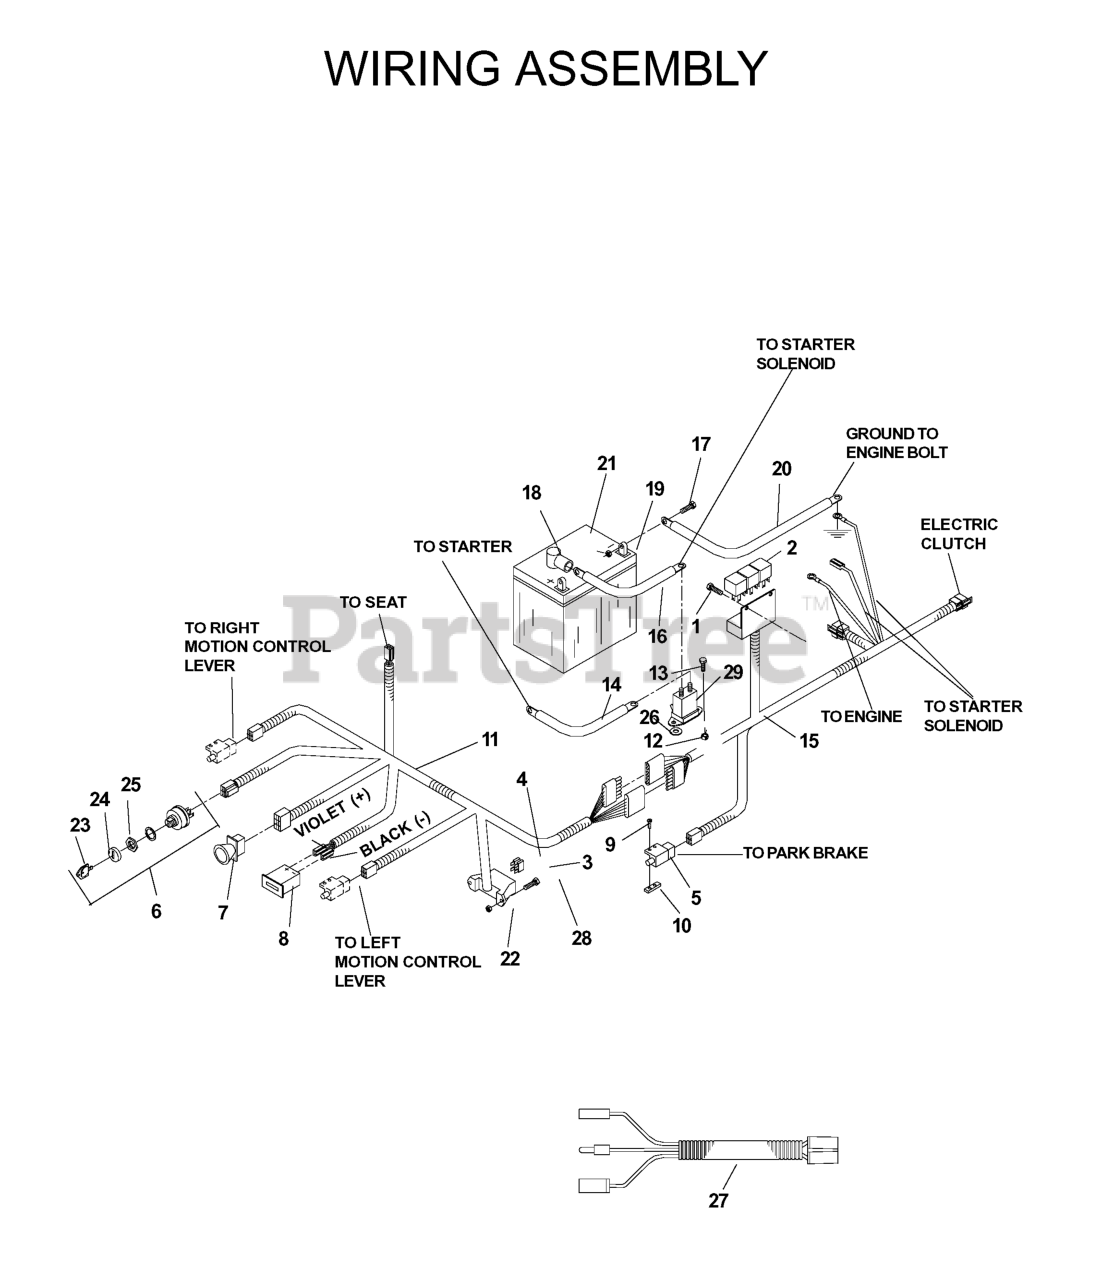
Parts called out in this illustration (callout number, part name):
1	SCREW #10 X 1/2 SELF TAPPING
3	FUSE, 7.5 AMP 32 VOLT ATO
4	FUSE, 20 AMP 32 VOLT ATO
5	SWITCH, INTERLOCK
6	IGNITION SWITCH KIT
7	RP.SWITCH, BLADE
8	HOUR METER
9	SCREW #10-24 X 5/8
10	TAPPED PLATE
11	CONSOLE HARNESS
12	NUT 1/4C CENTERLOCK
13	HCS 1/4C X 5/8
14	POST.CABLE LONG
15	FRAMES HARNESS
16	CABLE POSITIVE, LONG
17	HCS 5/16C X 3/4
19	NUT 5/16C CENTERLOCK
20	CABLE-NEGATIVE
21	BATTERY WET NOT SELLABLE
22	NUT 10-24 NYLOC
23	KEY-PADDED
24	CAP IGNITION NUT
25	DNO IGNITION NUT
26	WASHER 1/4 INT TOOTH
27	KAW PIGTAIL
28	SCREW, #1--24 X 1/2 SLOTTED
